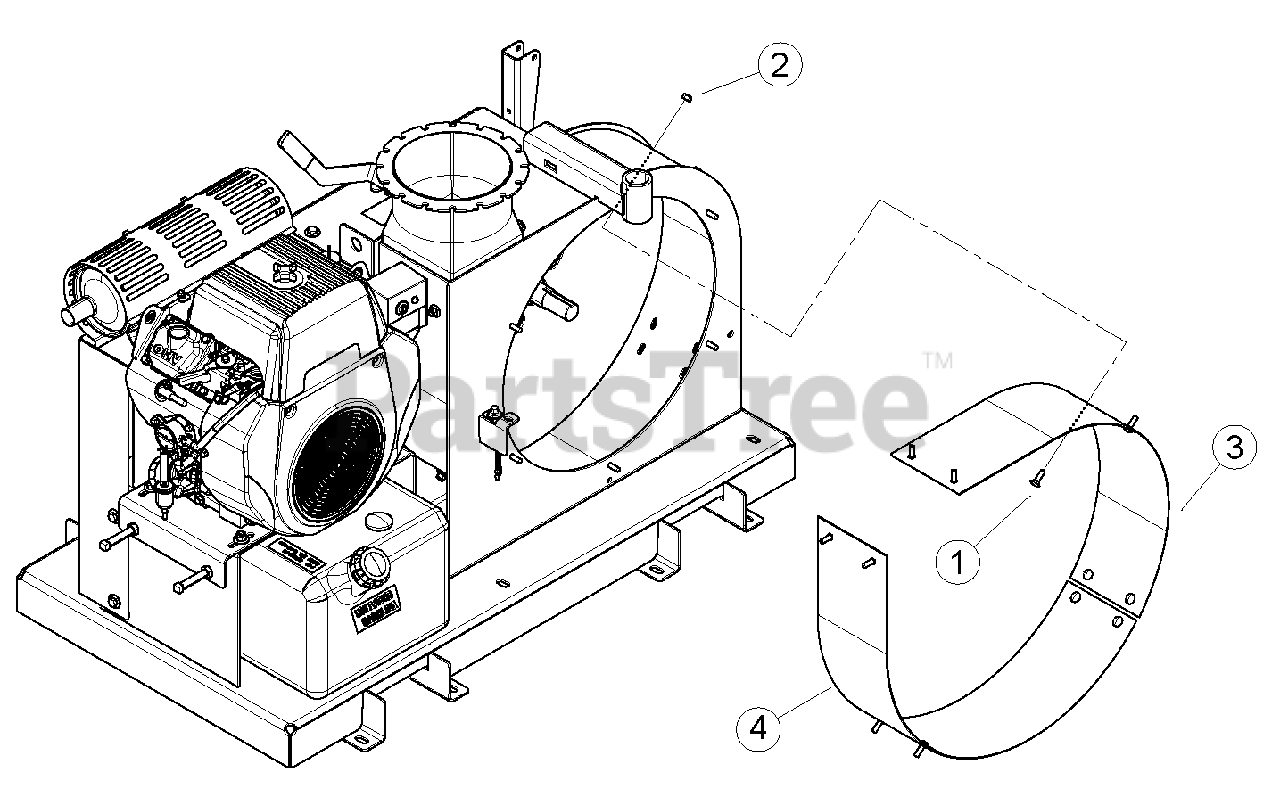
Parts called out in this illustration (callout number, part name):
1	BOLT, 5/16 X 1 CRG GR5 ZP
2	NUT, 5/16-18 NYLOCK-FLANGE
3	WRAP, HOUSING FAN
4	WRAP, HOUSING FAN
